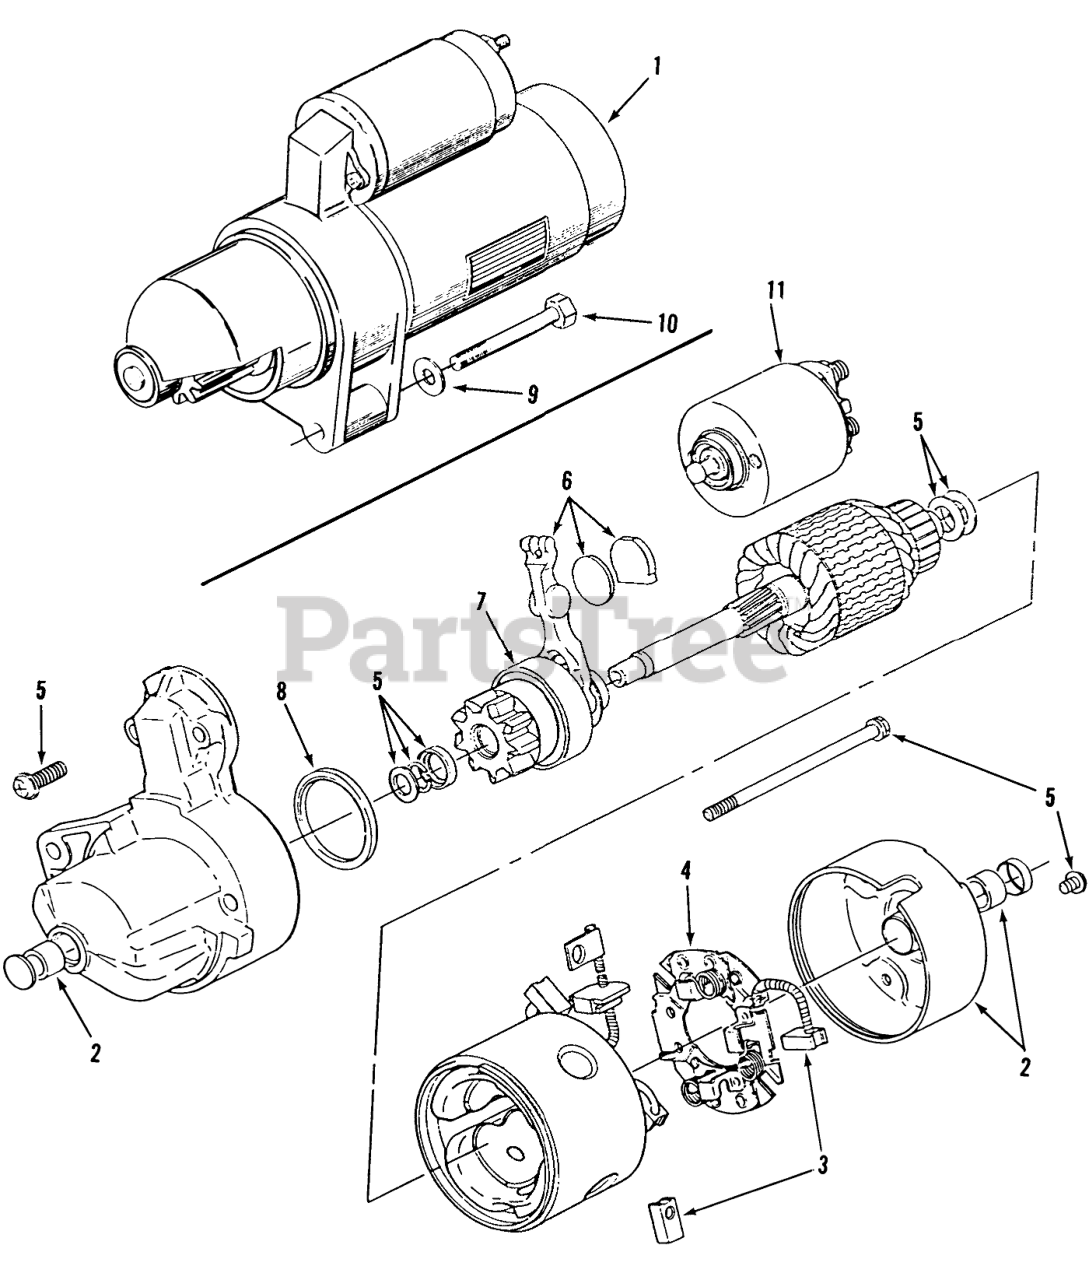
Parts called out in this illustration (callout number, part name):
1	Starter Assy
2	Bushing Kit (Includes Frt. Bushing and Rear Cap w/ Bushing)
3	Brush Kit (Includes Positive Brush (2) and Negitive Brush w/ Pigtail)
4	Brush Holder (Includes Brush Holder w/ Negitive Brush)
5	Hardware Kit (Includes Solenoid Screws (2), Brush Holder Screws (2), Thru Bolts (2), Armature Shims(2), Pinion Stop Collar and Pinion Retaining Ring)
6	Starter Shift Lever Kit (Includes Shift Lever, Wear Plate and Rubber Plug)
7	Starter Clutch (Includes Pinion Gear w/Clutch)
8	Dust Seal
9	Washer
10	Bolt
11	Starter Solenoid Kit (Includes Solenoid, Spring and Plunger)
